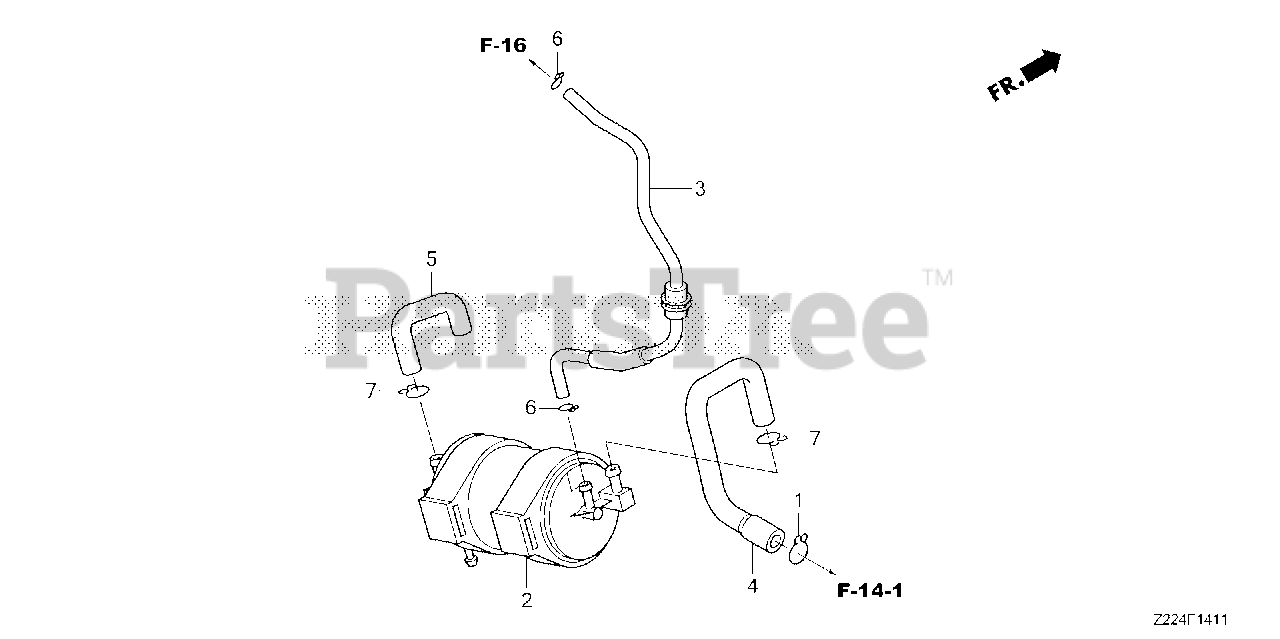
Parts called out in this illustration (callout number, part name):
1	CLIP, BREATHER TUBE
2	CANISTER ASSY.
3	TUBE CANISTER CHARGE
4	TUBE, CANISTER PURGE
5	TUBE, CANISTER AIR
6	CLIP, TUBE (B8)
7	CLIP, TUBE (B12) Use from Engine SN 2086984.
